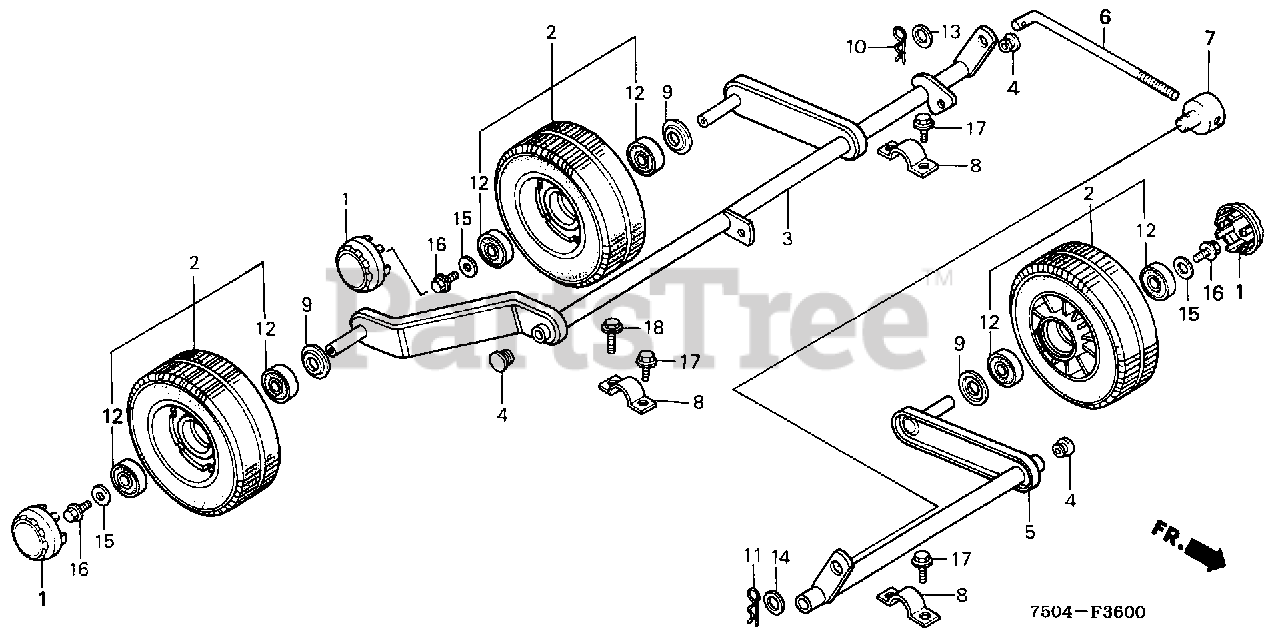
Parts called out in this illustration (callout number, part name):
1	CAP, WHEEL
2	WHEEL (6-2.0)
3	SHAFT, R. (NOT AVAILABLE)
4	CAP, WHEEL SHAFT
5	SHAFT, L. WHEEL
6	BAR, ADJUSTING
7	PIN, ADJUSTING (NOT AVAILABLE)
8	BRACKET, R. SHAFT
9	WASHER, SPECIAL (12MM)
10	PIN, LOCK (2.3MM)
11	PIN, LOCK (2.3MM)
12	BEARING, RADIAL BALL
13	WASHER, FLAT (12MM)
14	WASHER, PLAIN (14MM)
15	WASHER, PLAIN (6MM)
16	BOLT, FLANGE (6X12)
17	BOLT, FLANGE (8X14)
18	BOLT, FLANGE (8X20)
